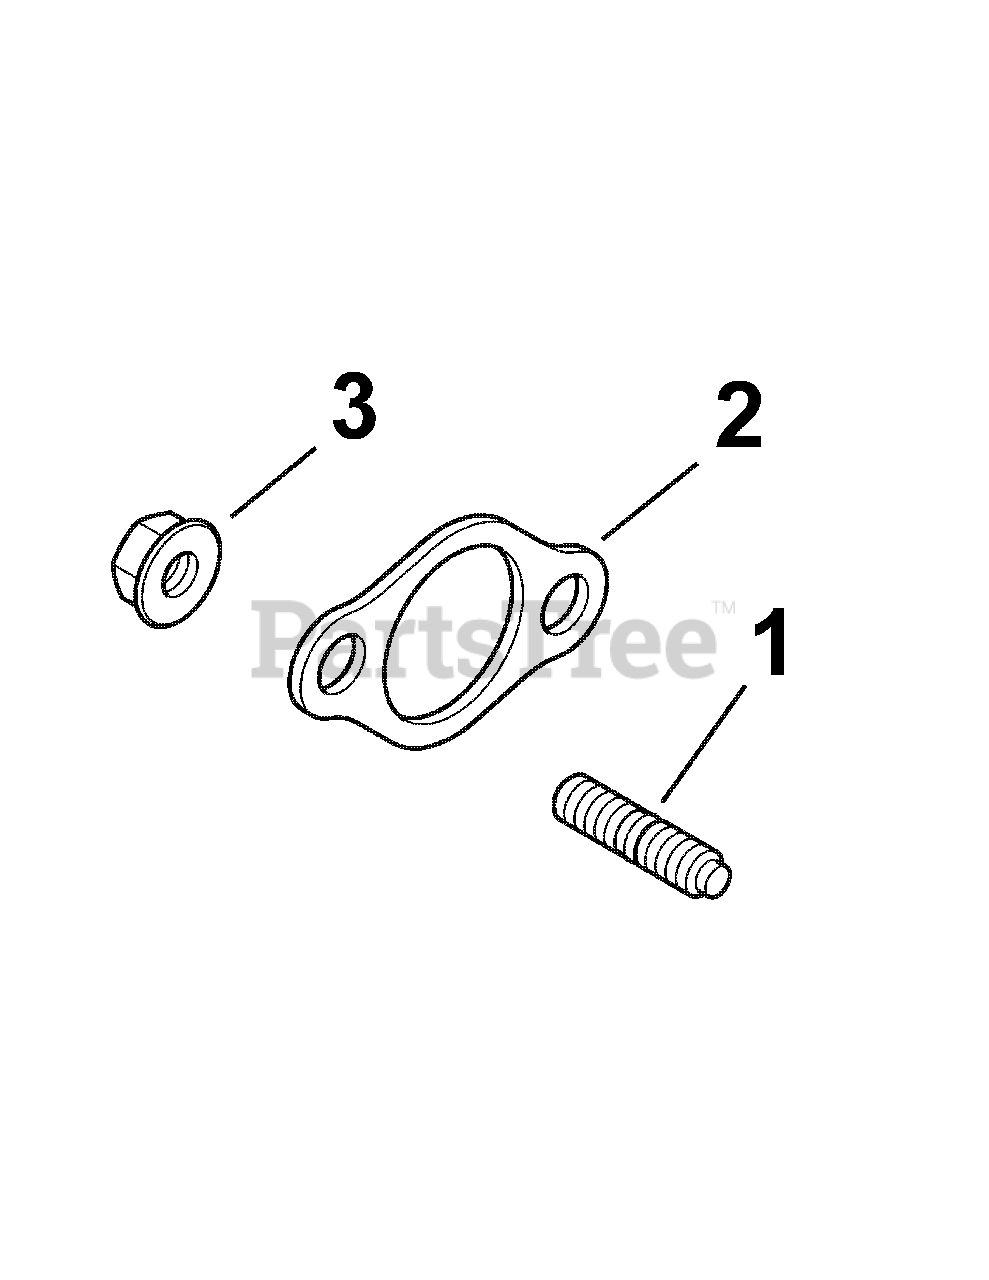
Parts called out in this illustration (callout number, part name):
1	Stud, M8 x 1.25 x 33
2	Gasket, Exhaust
3	Nut, Flg, M8 x 1.25
